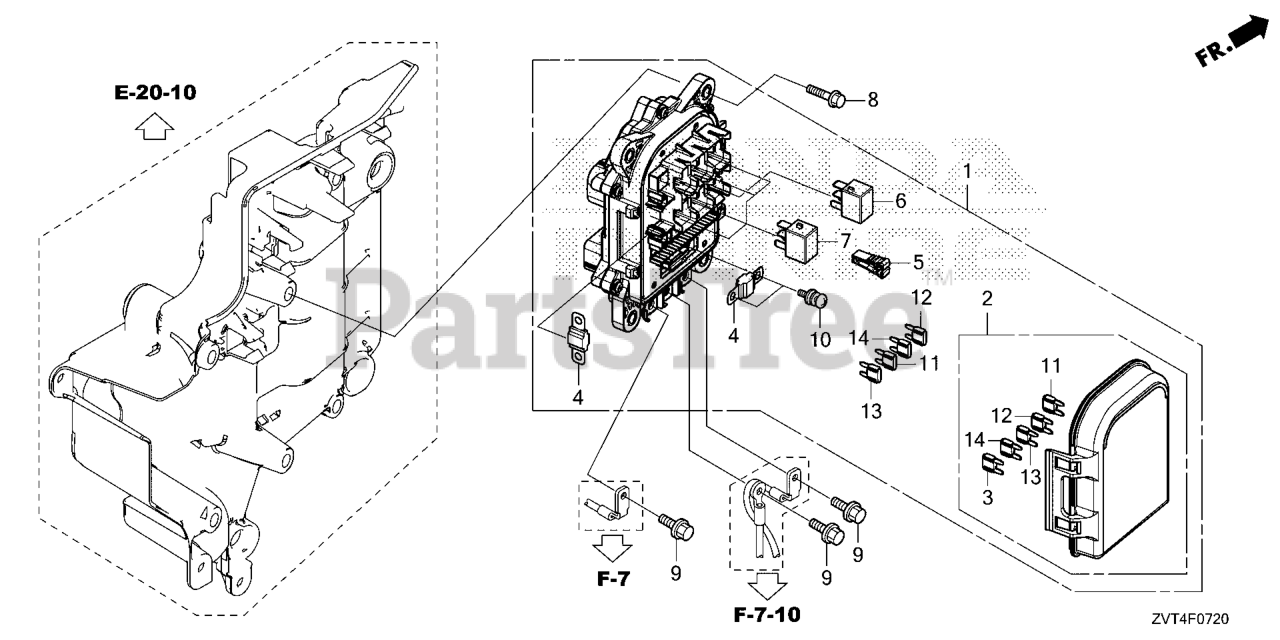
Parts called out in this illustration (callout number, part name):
1	BOX ASSY., JUNCTION
2	COVER, FUSE
3	FUSE, BLADE (3A)
4	FUSE, BLOCK (100A) (L-TYPE)
5	PULLER, MINI FUSE
6	RELAY ASSY., FUEL PUMP (DENSO)
7	RELAY ASSY., POWER (12V-20A) (MICRO ISO 4P)
8	BOLT, FLANGE (6X20)
9	BOLT, FLANGE (6X12)
10	SCREW-WASHER (5X15)
12	FUSE, MINI (10A)
13	FUSE, MINI (15A)
14	FUSE, MINI (30A)
